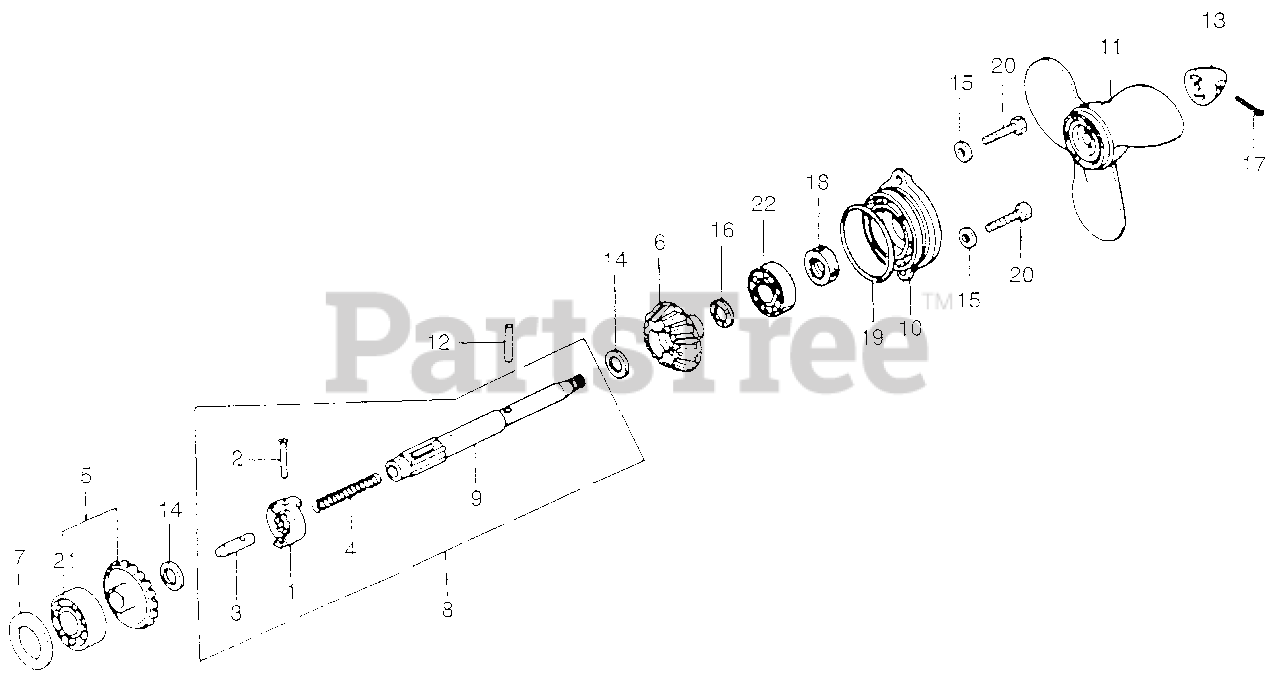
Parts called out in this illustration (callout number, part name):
1	SHIFTER, CLUTCH
2	PIN, SHIFTER (4X35)
3	SLIDER, SHIFT
4	SPRING, SHIFT
5	GEAR, FR. BEVEL
6	GEAR, RR. BEVEL
7	SHIM A, GEAR (0.10MM)
7	SHIM B, GEAR (0.15MM)
8	SHAFT, PROPELLER
9	SHAFT, PROPELLER
10	HOLDER, PROPELLER SHAFT *B9* (ATLANTIS BLUE) (NOT AVAILABLE)
11	PROPELLER, THREE-BLADE *NH283* (STIN GRAY)
12	PIN, SHEAR
13	CAP, PROPELLER
14	WASHER (17MM)
15	WASHER, PLAIN (6MM)
16	WASHER C, GEAR (2.10MM)
16	WASHER D, GEAR (2.15MM)
17	PIN, COTTER (3MM)
18	SEAL, WATER (17MM)
19	O-RING (66X2.5)
20	BOLT, HEX. (6X20)
21	BEARING, RADIAL BALL (6005)
22	BEARING, RADIAL BALL (6203)
